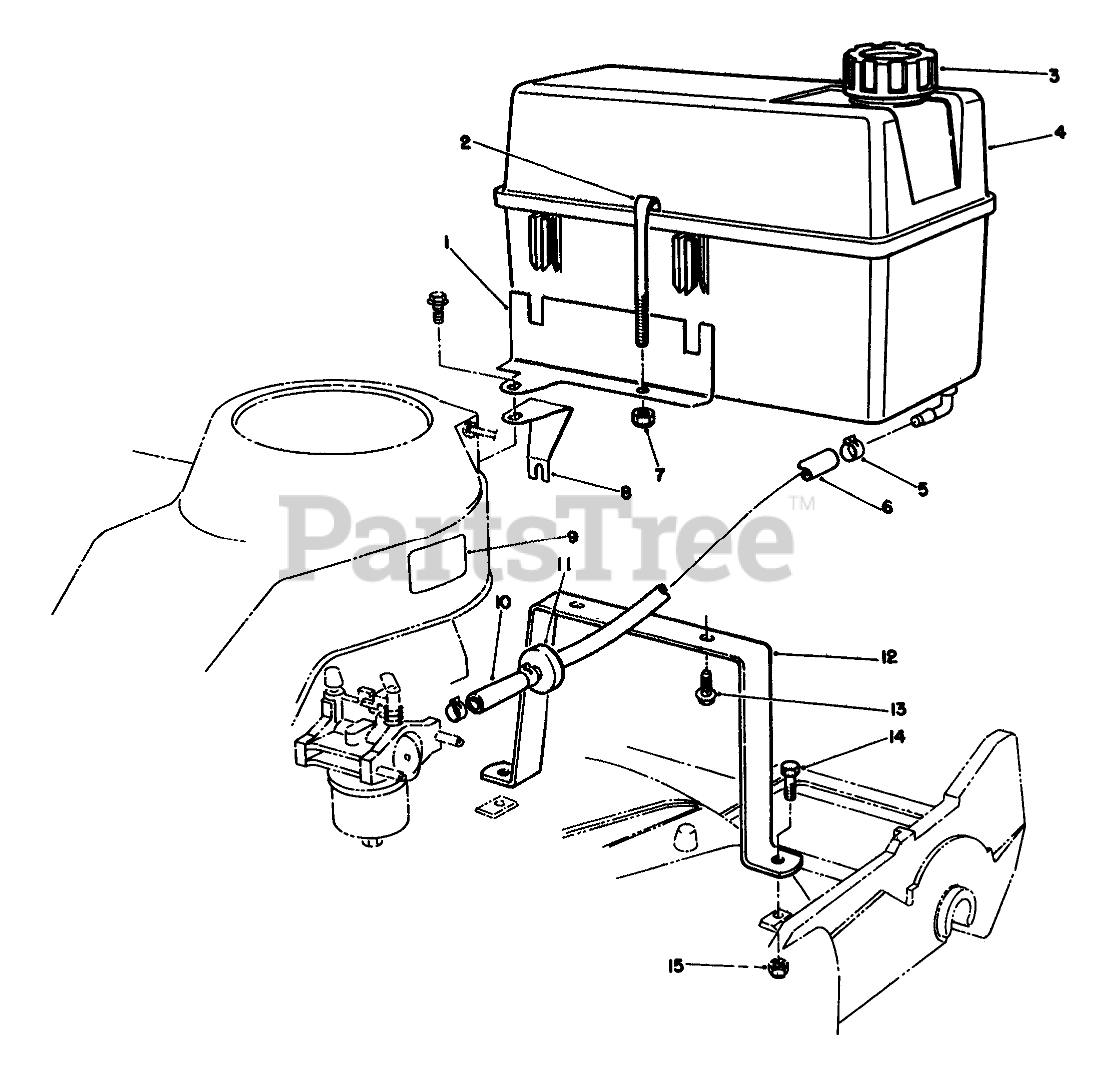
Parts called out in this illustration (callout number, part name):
1	Bracket Tank
2	RETAINER - FUEL TANK
3	GAS CAP ASM
4	Tank-Gas
5	CLAMP-FUEL LINE
6	HOSE-FUEL
7	NUT-LOCK, NI
8	Support-Bracket
9	DECAL - FUEL
10	LINE-GAS
11	FILTER-FUEL
12	TANK BASE
13	SCREW-HWH
14	SCREW-HH
15	NUT-LOCK, NI
